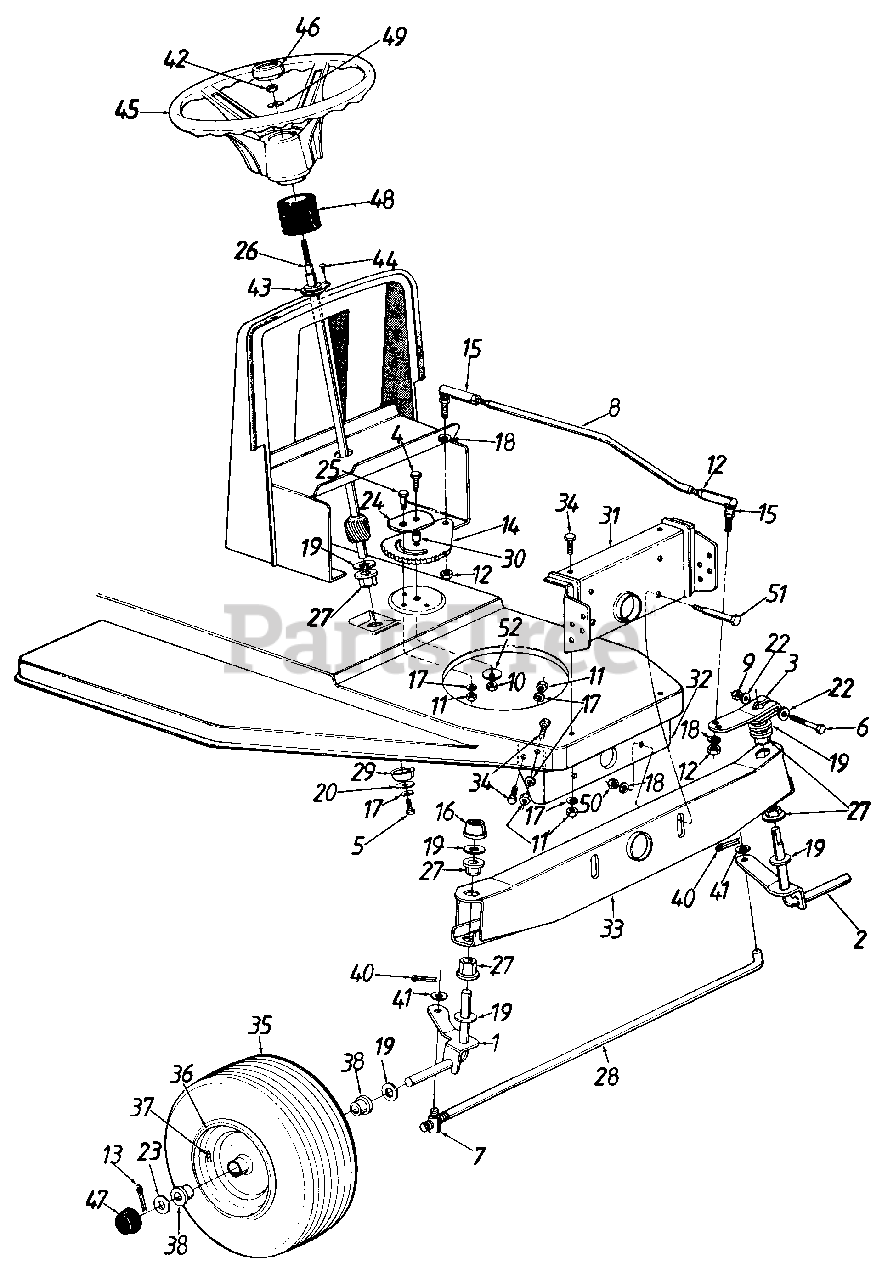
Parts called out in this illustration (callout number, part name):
1	Front Axle Ass'y.-R.H.
2	Front Axle Ass'y.-L.H.
3	Steering Arm
4	Hex Bolt 3/8-24 x 1" Lg.
5	Hex Bolt 5/16-18 x .62"
6	Hex Bolt 5/16-24 x 2" Lg.
7	Ferrule
8	Steering Drag Link
9	Hex L-Nut 5/16-24 Thd.
10	Hex Nut 3/8-24 Thd.
11	Hex Nut 5/16-18 Thd.
12	Hex Jam Nut, 3/8-24
13	Cotter Pin 1/8 Dia.
14	Steering Gear Segment
15	Drag Link Ball Joint 3/8-24 Thd.
17	L-Wash. 5/16" I.D.
18	L-Wash. 3/8" I.D.
19	Fl-Wash. .64" I.D. x 1.24"
20	Fl-Wash. .340" I.D. x 1.125"
22	Spr. Wash. .32 I.D. x .62
23	Fl-Wash. .635 I.D. x 1.585
24	Retainer Plate
25	Shld. Bolt .437 Dia. x .350
26	Steering Shaft
27	Hex Flange Brg. .634 Dia.
28	Tie Rod 19.1 Lg.
29	Spacer .985 I.D.
30	Spacer .380 I.D.
31	Front Pivot Bar Support 8rkt.
32	Rear Pivot Bar Support Brkt.
33	Pivot Bar Ass'y.
34	Hex Bolt 5/16-18 x .75" Lg.
35	Front Wheel Ass'y. Comp. 13 x 6
37	Air Valve
38	Flange Bearing .632 I.D.
40	Cotter Pin 3/32" Dia.
41	Fl-Wash. .406" l.D. x .75"
42	Hex L-Nut 5/16-24 Thd.
43	Steering Column Brg.
44	Cr-Sunk Scr. #10 x 5/8" Lg.
45	Steering Wheel
46	Steering Wheel Cap
47	Hub Cap
48	Bellow Steering Column
49	Bell-Wash. .345 I.D. x .88
50	Hex Nut 3/8-16 Thd.
51	Shld. Bolt 1/2" Dia. x 2.32"
52	Bell-Wash. .39" l.D. x 1.4" .
